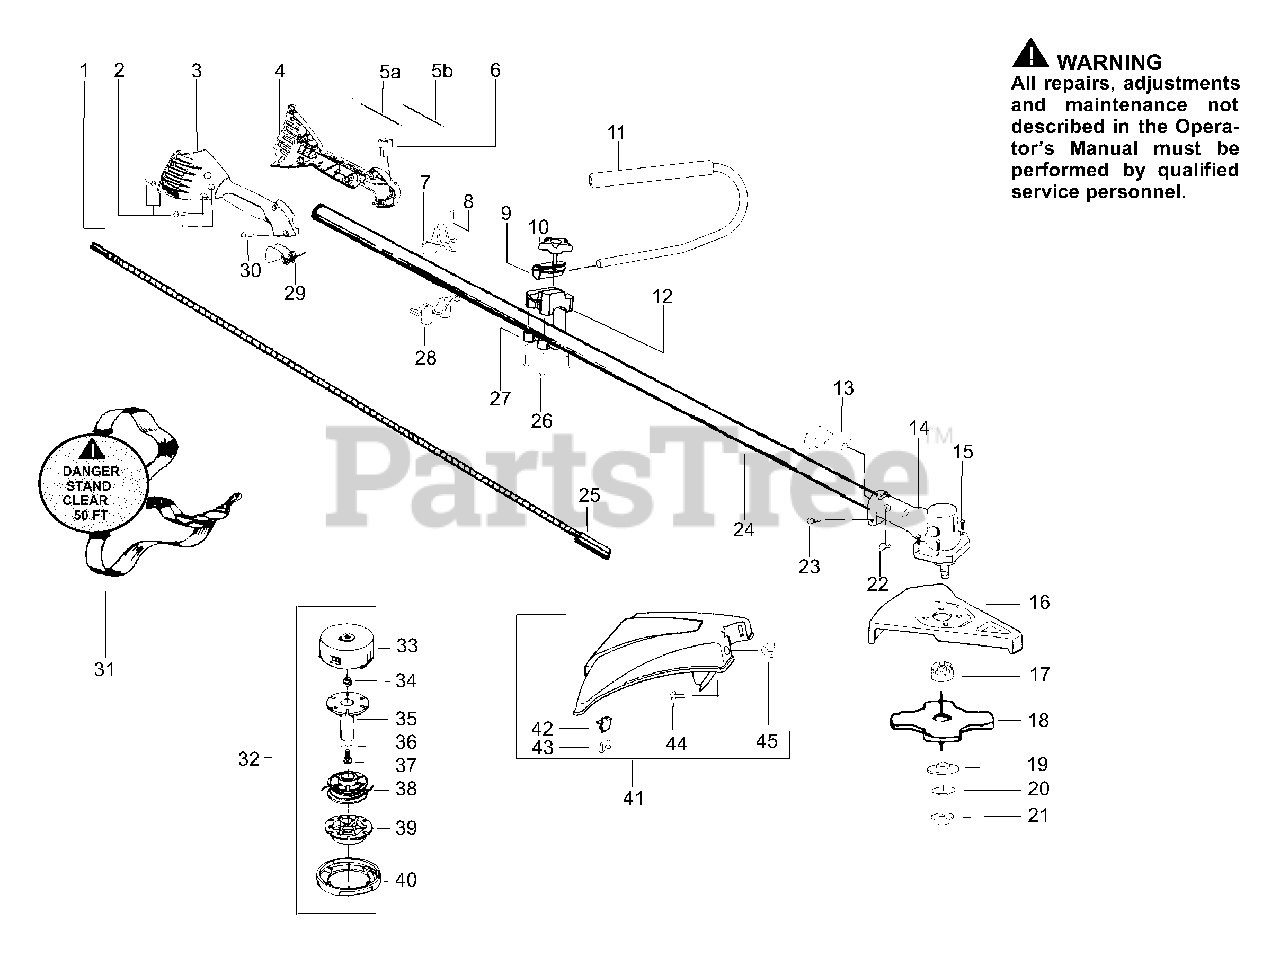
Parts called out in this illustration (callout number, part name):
1	Screw-alignment
2	Screw-10-24
3	Throttle hsg-right
4	Kit-Left Throttle hsg.
5A	Assy-Wire Assy-Front Wire
5B	Assy-Wire Assy-Front Wire (Upper)
6	Kit-Switch
7	Clamp-Harness (upper)
9	Clamp-Handlebar
10	Knob
11	Assy.-Handlebar
12	Base-Clamp
13	Bracket-Shield
14	Kit-Gearbox
16	Kit-Metal Shield
17	Dust cup
18	Accy.-Weed Blade
20	Washer-Belleville
21	Nut-Flange
24	Assy.-Driveshaft
25	Shaft-Flex Drive
27	Kit-Clamp-Tube
28	Clamp-Harness (lower)
29	Lever-Throttle
31	Shoulder Strap
32	Accy.-Head TNG 2
33	Assy.-Hub/Arbor
35	Kit-Locking Plate
37	Screw
38	Accy.-Spool TNG 2
39	Button-Release
41	Kit-Shield Assy.
42	Limiter-Line
43	Screw
45	Wingnut
